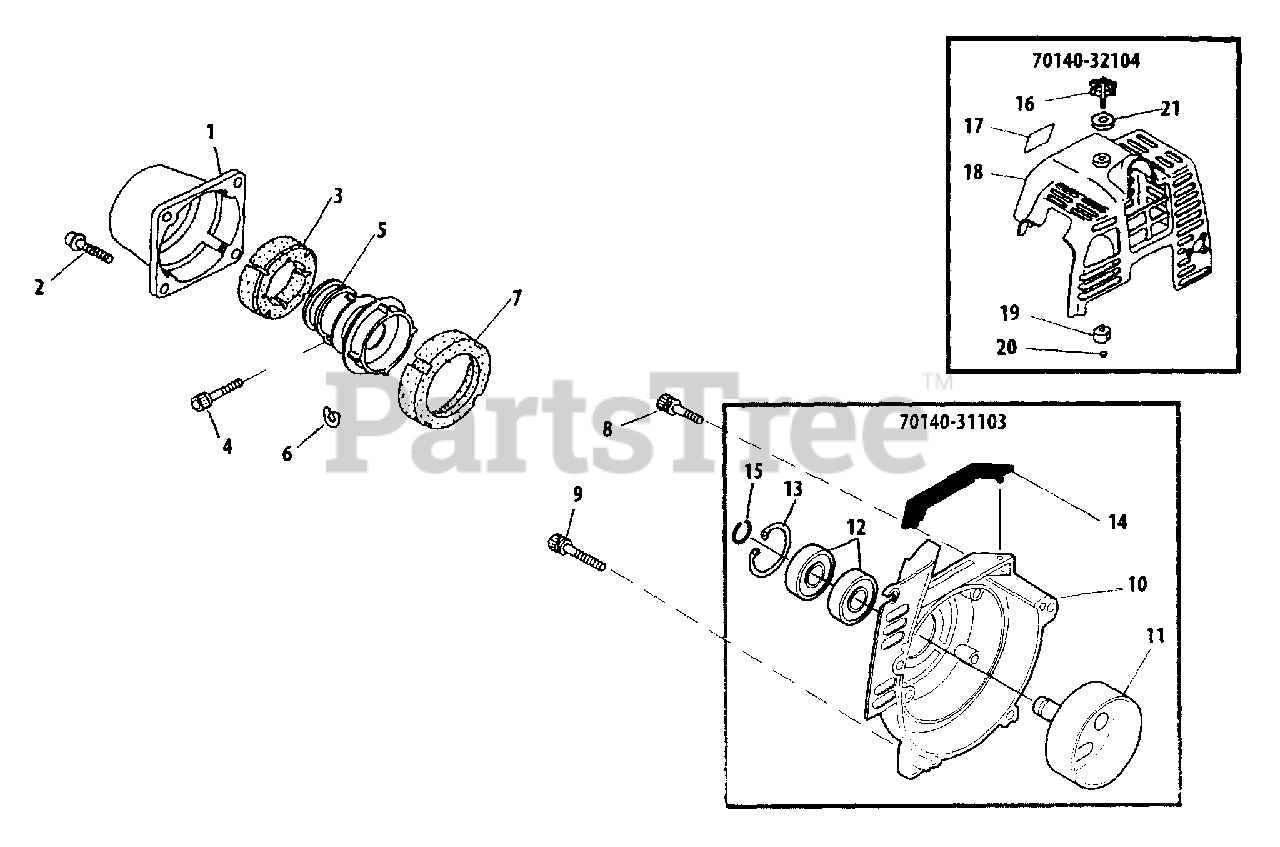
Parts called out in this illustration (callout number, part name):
1	CAP
2	SCREW - 5X16
3	CUSHION - FRONT
4	SCREW - 5X25
5	CLAMP, MAIN PIPE
6	SHIM
7	CUSHION - REAR
8	SCREW - 5X16
9	SCREW - 5X35
10	CASE, FAN
11	DRUM, CLUTCH
12	BEARING, BALL - 6000
13	RING, RETAINING - 26
14	CUSHION
15	RING, RETAINING
16	THUMBSCREW
17	LABEL
18	COVER, ENGINE
19	INSULATOR
20	CLIP
21	WASHER - CONICAL
70140-31103	FAN CASE ASSY
70140-32104	ENGINE COVER KIT - RED
